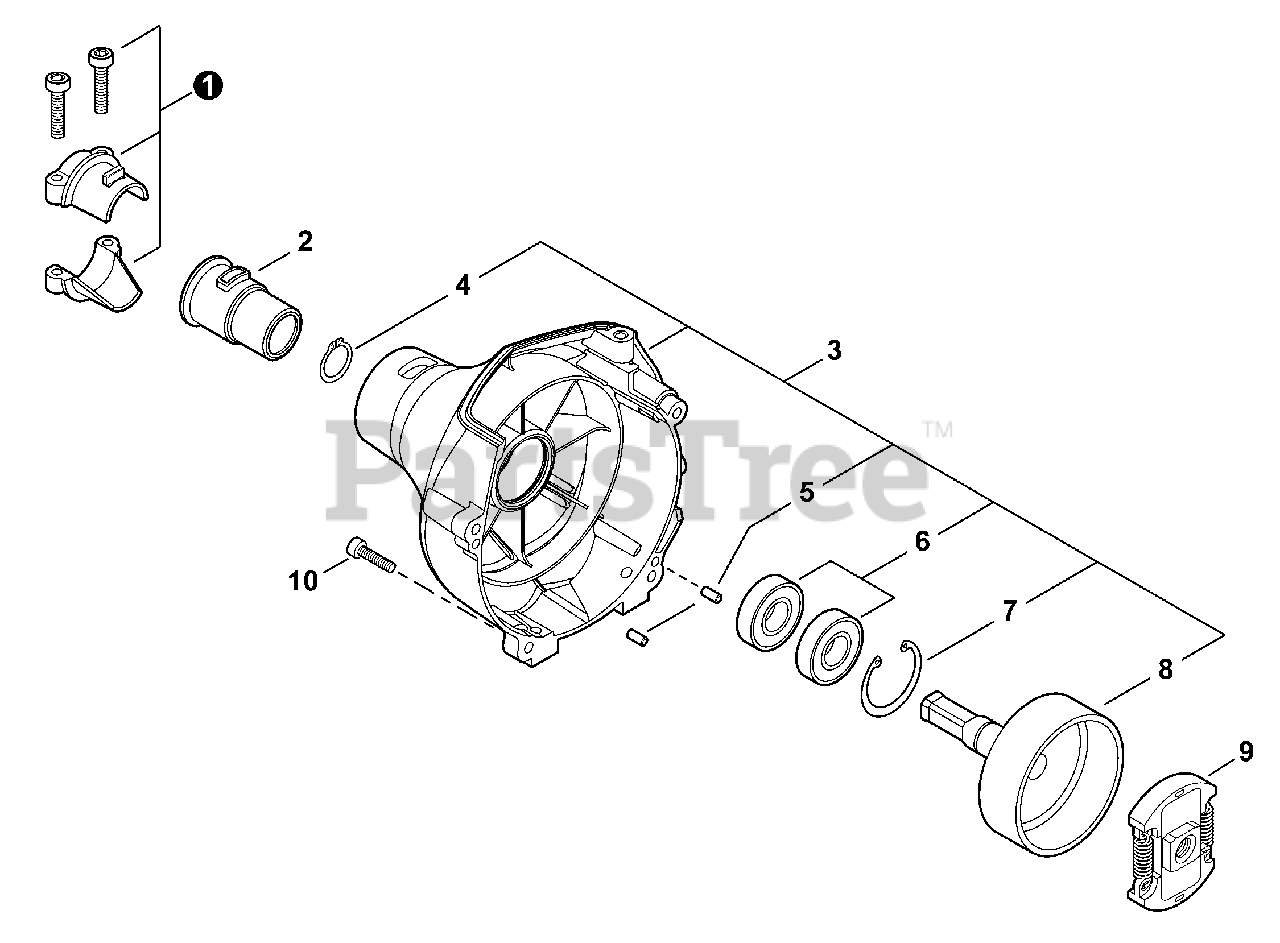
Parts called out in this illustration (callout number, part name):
1	HOLDER KIT
2	CUSHION Ø25
3	COVER ASSY, FAN
4	RING, SNAP 12
5	PIN, LOCATING 4×8
6	BEARING, BALL 6001
7	RING, SNAP 28
8	DRUM, CLUTCH
9	CLUTCH ASSY
10	BOLT, TORX 4×16
